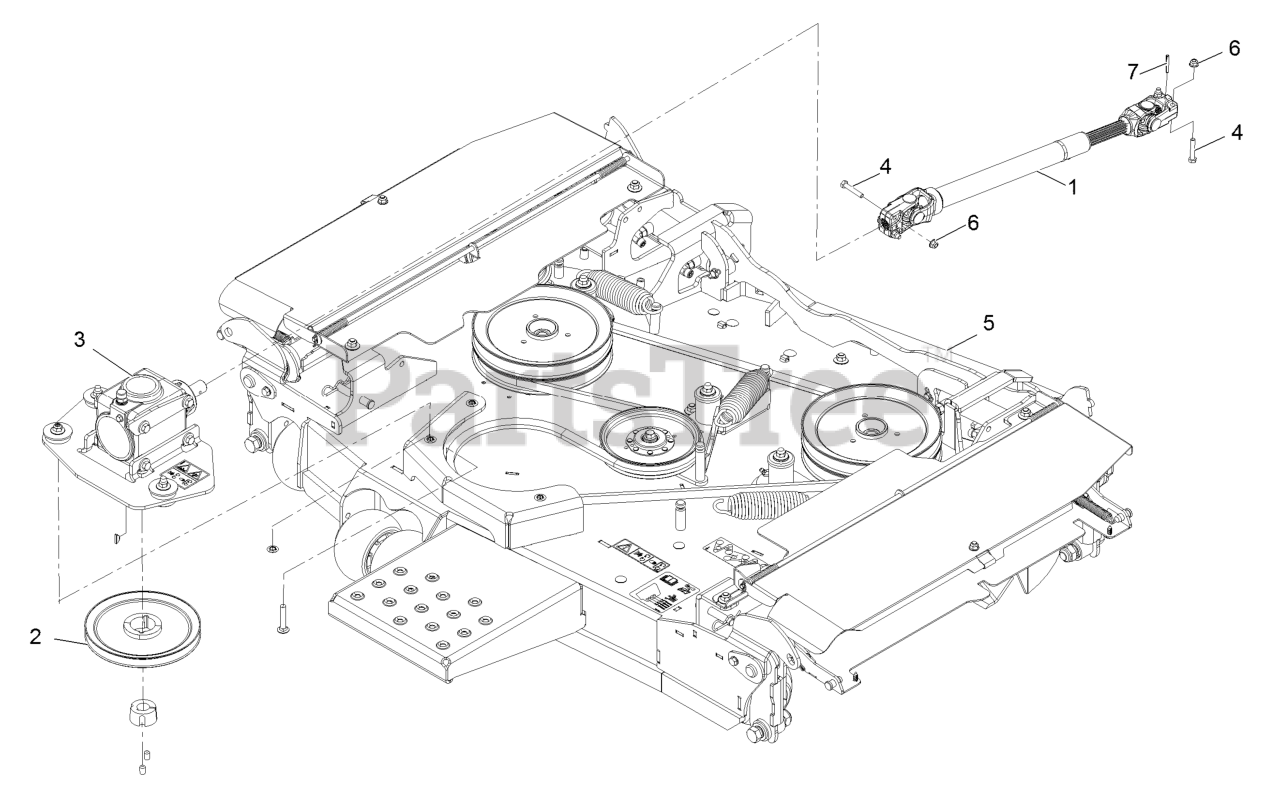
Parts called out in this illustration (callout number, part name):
1	Driveshaft ASM
3	Gearbox ASM
4	Screw-HH 5/16-18 X 1 3/4
6	Nut-Nyloc 5/16-18
7	Pin-Roll
